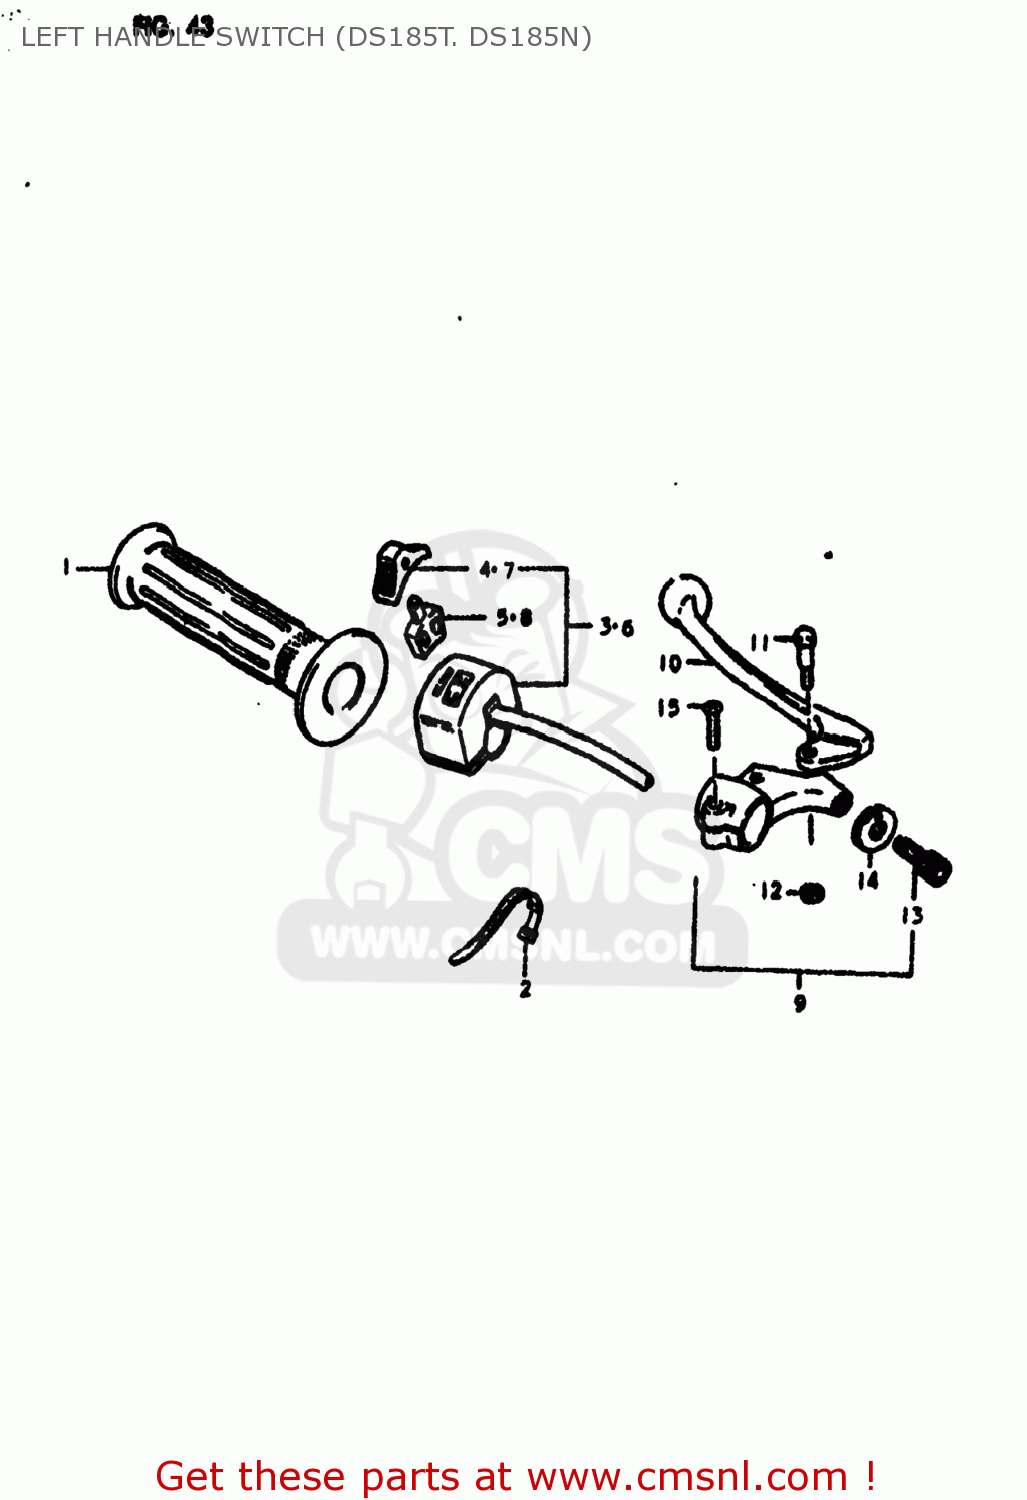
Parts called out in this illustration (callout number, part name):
1	GRIP,L
2	CLAMP(L:120)
3	SWITCH,DIMMER
4	KNOB,HANDLE SWITCH
5	BLOCK,LIGHTING/DIMMER
6	SWITCH,DIMMER
7	KNOB,LIGHTING & DIMMER
8	BLOCK,LIGHTING/DIMMER
9	LEVER ASSY,CLUTCH
10	LEVER,CLUTCH
11	BOLT,LEVER
12	NUT 6MM
13	ADJUSTER,CABLE
14	NUT,CABLE ADJUSTER
15	SCREW
